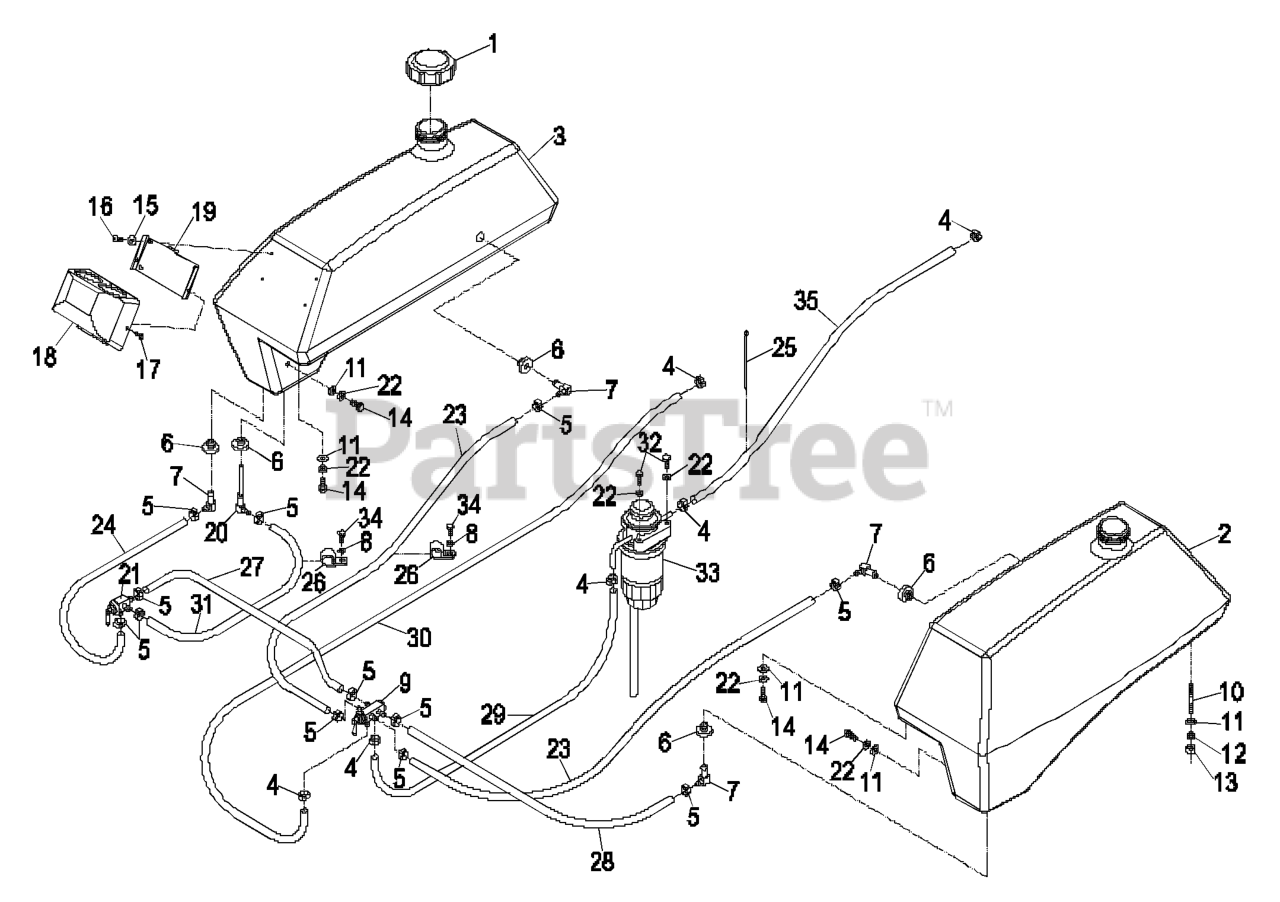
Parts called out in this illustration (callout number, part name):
1	CAP,DIESEL FUEL TANK
4	CLAMP-HOSE, FUEL
5	CLAMP-HOSE, FUEL
7	ELBOW-90 DEG
8	WASHER-LOCK
9	VALVE-FUEL, DUAL FLOW
10	STUD
11	WASHER-PLAIN
12	SPRING-TANK, FUEL
13	NUT-LOCK, NI
14	SCREW-HH
15	WASHER-SPRING
16	SCREW-PPH
18	COVER,GAUGES
19	BRACKET,GAUGE MOUNT
21	VALVE,FUEL DIVERTER 90 DE
22	WASHER-LOCK
24	HOSE-FUEL
25	TIE-PLASTIC
26	CLIP-LOOM
28	FUEL LINE,19.0
29	HOSE-FUEL
30	HOSE-OVERFLOW
32	SCREW-HH
33	Fuel Filter
34	SCREW-HH
